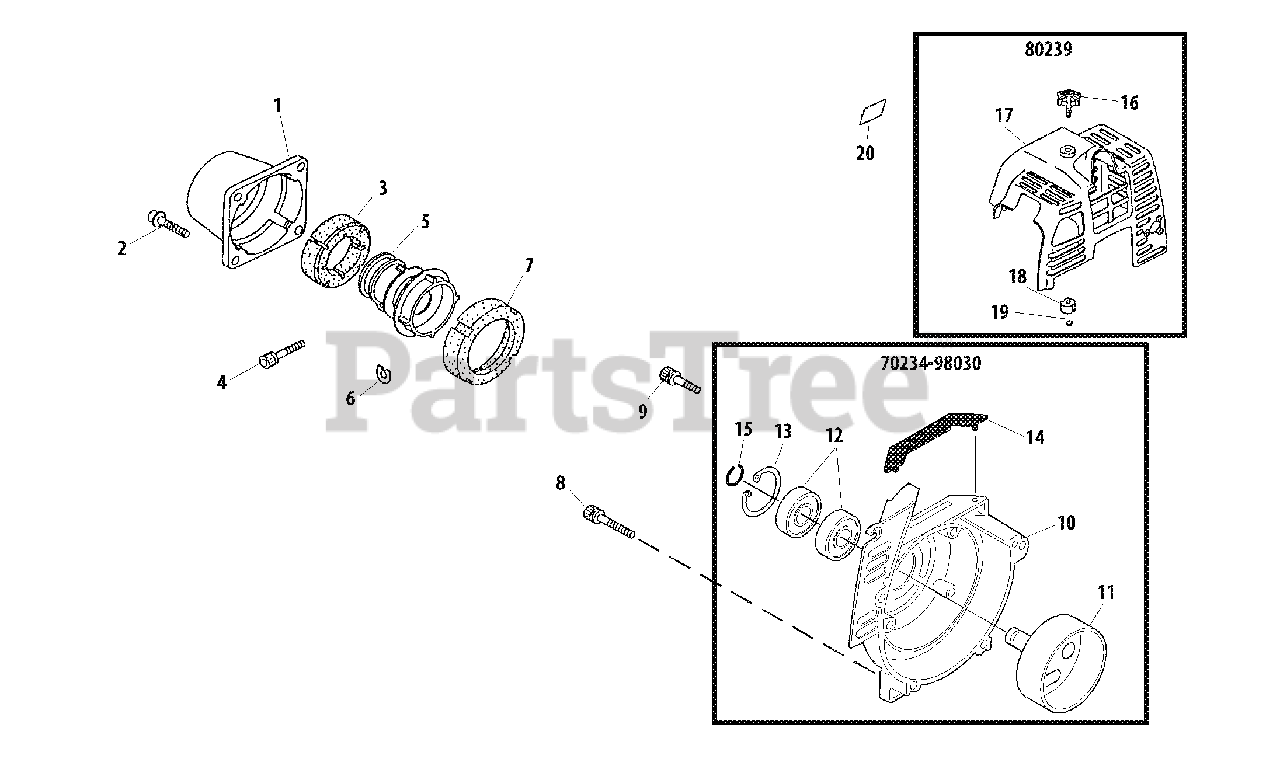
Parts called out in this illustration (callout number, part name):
1	COVER, AV CUSHION (RED)
2	BOLT M5×16
3	CUSHION, FRONT
4	BOLT M5×25
5	JOINT
6	D-WASHER
7	HOLDER, REAR CUSHION
8	BOLT M5×35
9	BOLT M5×16
10	COVER, FAN
11	DRUM, CLUTCH
12	BEARING, BALL 6000ZZ
13	RING, SNAP Ø26
14	CUSHION
15	RING, SNAP WR10
16	THUMBSCREW
17	COVER, ENGINE
18	INSULATOR 5 MM
19	CLIP
70234-98030	FAN CASE ASSY
80239	ENGINE COVER KIT
